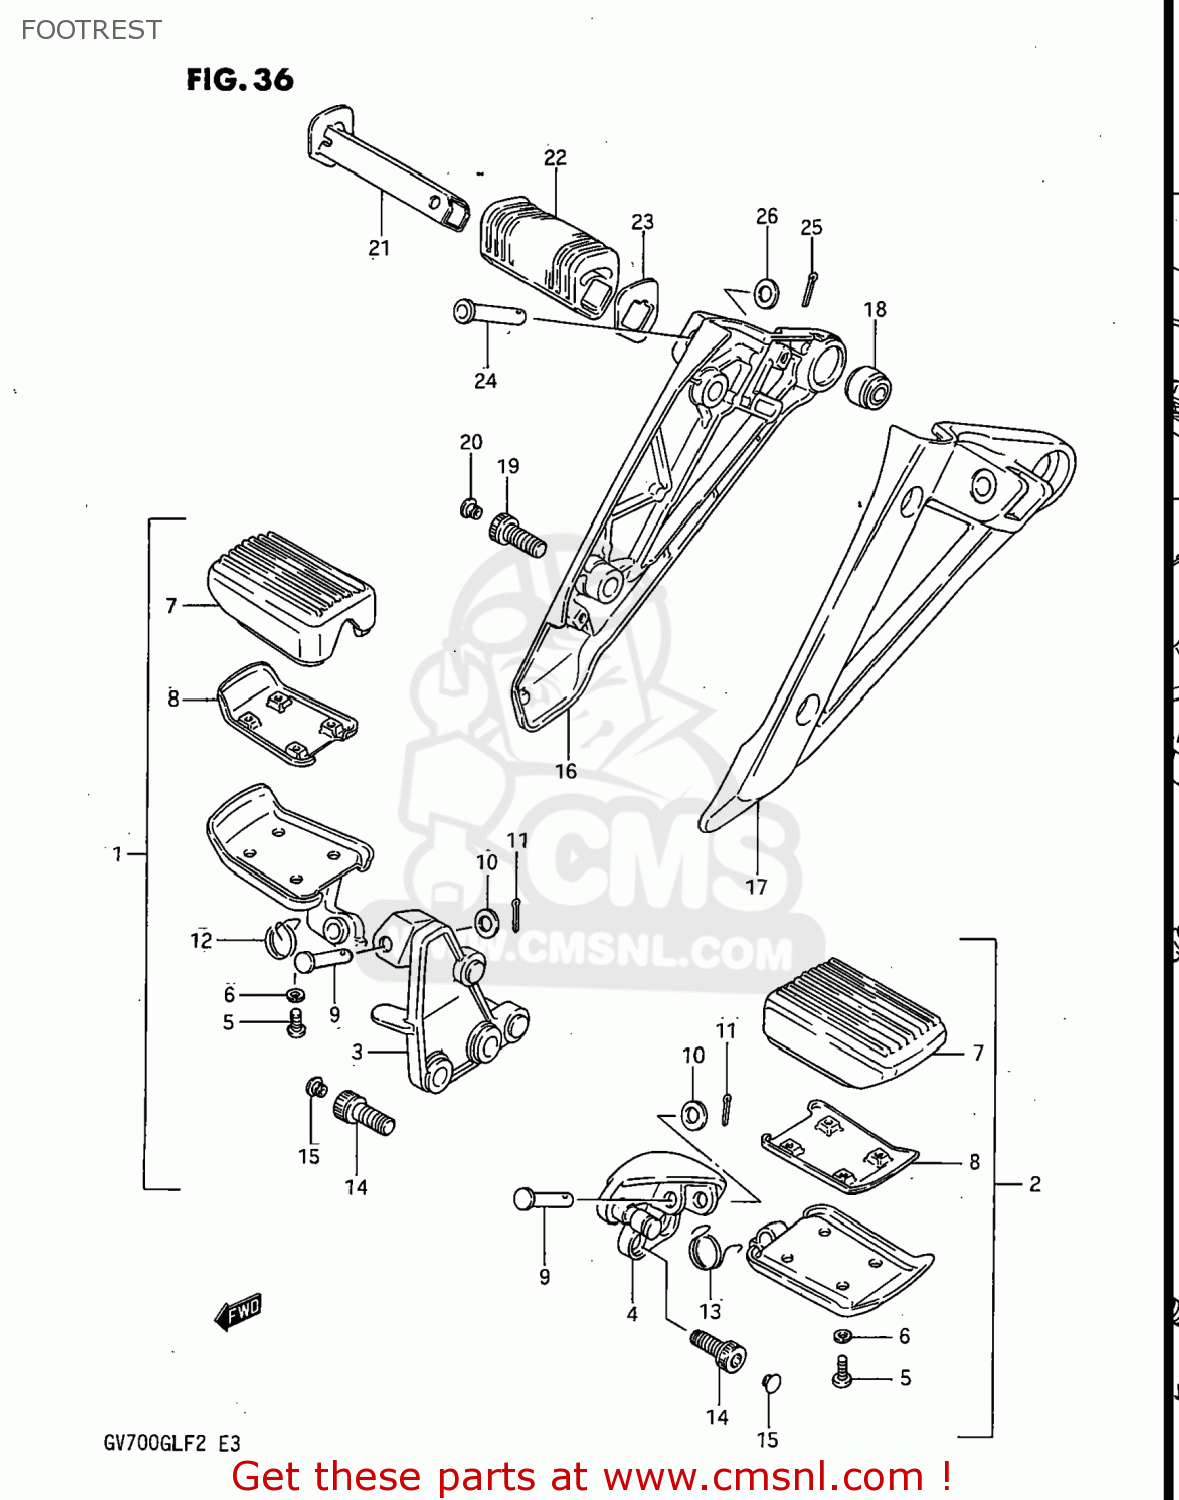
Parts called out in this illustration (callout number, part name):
1	FOOTREST ASSEMBLY,FRONT,RIGHT
2	FOOTREST ASSEMBLY,FRONT,LEFT
3	BAR,FRONT FOOTREST,RIGHT
4	BAR,FRONT FOOTREST,LEFT
5	SCREW
6	LOCK WASHER
7	RUBBER,FR FOOTREST
9	PIN
10	WASHER
11	PIN 20X20
12	SPRING
13	SPRING
14	BOLT
15	CAP
16	BRACKET,MUFFLER,RIGHT
17	BRACKET,MUFFLER,LEFT
18	BUSH(10.2X25X19)
19	BOLT
20	CAP
21	BAR,REAR FOOTREST,LEFT
22	RUBBER,REAR FOOTREST
23	WASHER,REAR FOOTREST RUBBER
24	PIN
25	PIN 20X20
26	WASHER
